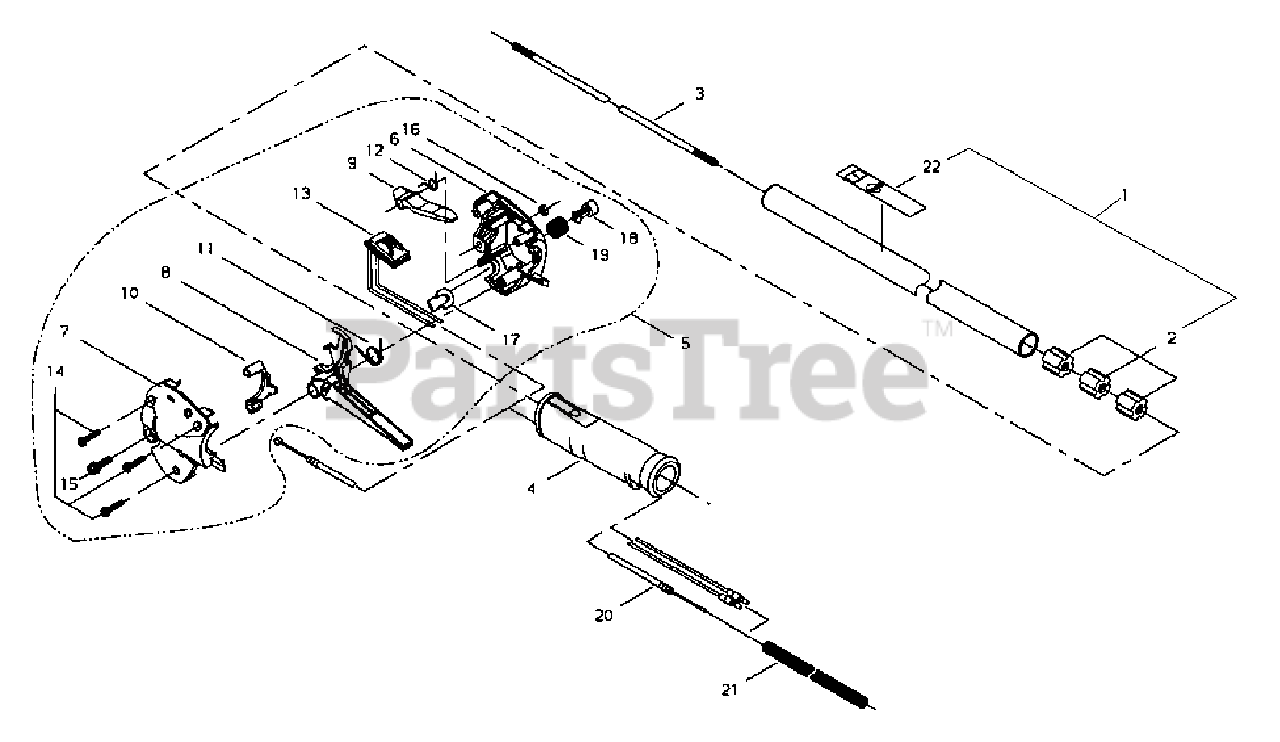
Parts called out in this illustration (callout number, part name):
1	MAIN PIPE ASSY
2	BUSHING
3	MAINSHAFT
4	GRIP
5	THROTTLE CONTROL ASSY
6	CONTROL HANDLE - RIGHT
7	CONTROL HANDLE - LEFT
8	TRIGGER, THROTTLE
9	LEVER, THROTTLE LOCKOUT
10	LOCKOUT, THROTTLE
11	SPRING, THROTTLE RETURN
12	SPRING, THROTTLE LOCKOUT
13	SWITCH, ON-OFF
14	SCREW, TAPPING M4×20
15	SCREW M5×20
16	NUT M5
17	PLUG
18	BUTTON, THROTTLE LOCK
19	SPRING, COMPRESSION
20	CABLE, THROTTLE
21	TUBE, PLASTIC PROTECTIVE
22	LABEL, CAUTION
23	LABEL - CAUTION
